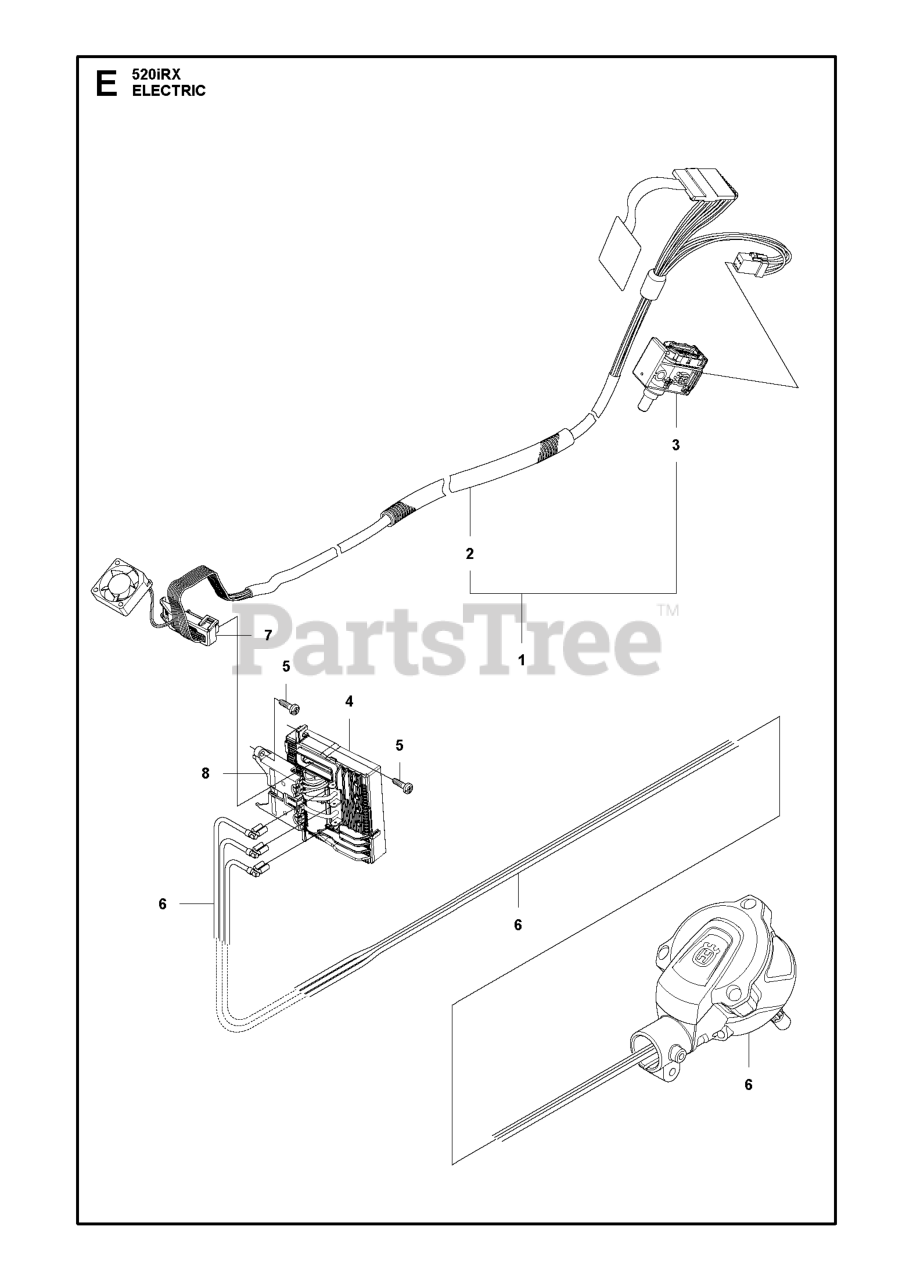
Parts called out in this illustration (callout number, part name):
3	TRIGGER SWITCH IPX4
4	CONTROL UNIT
6	MOTOR ASSY BLDC BLADE
8	CONNECTOR BATTERY
